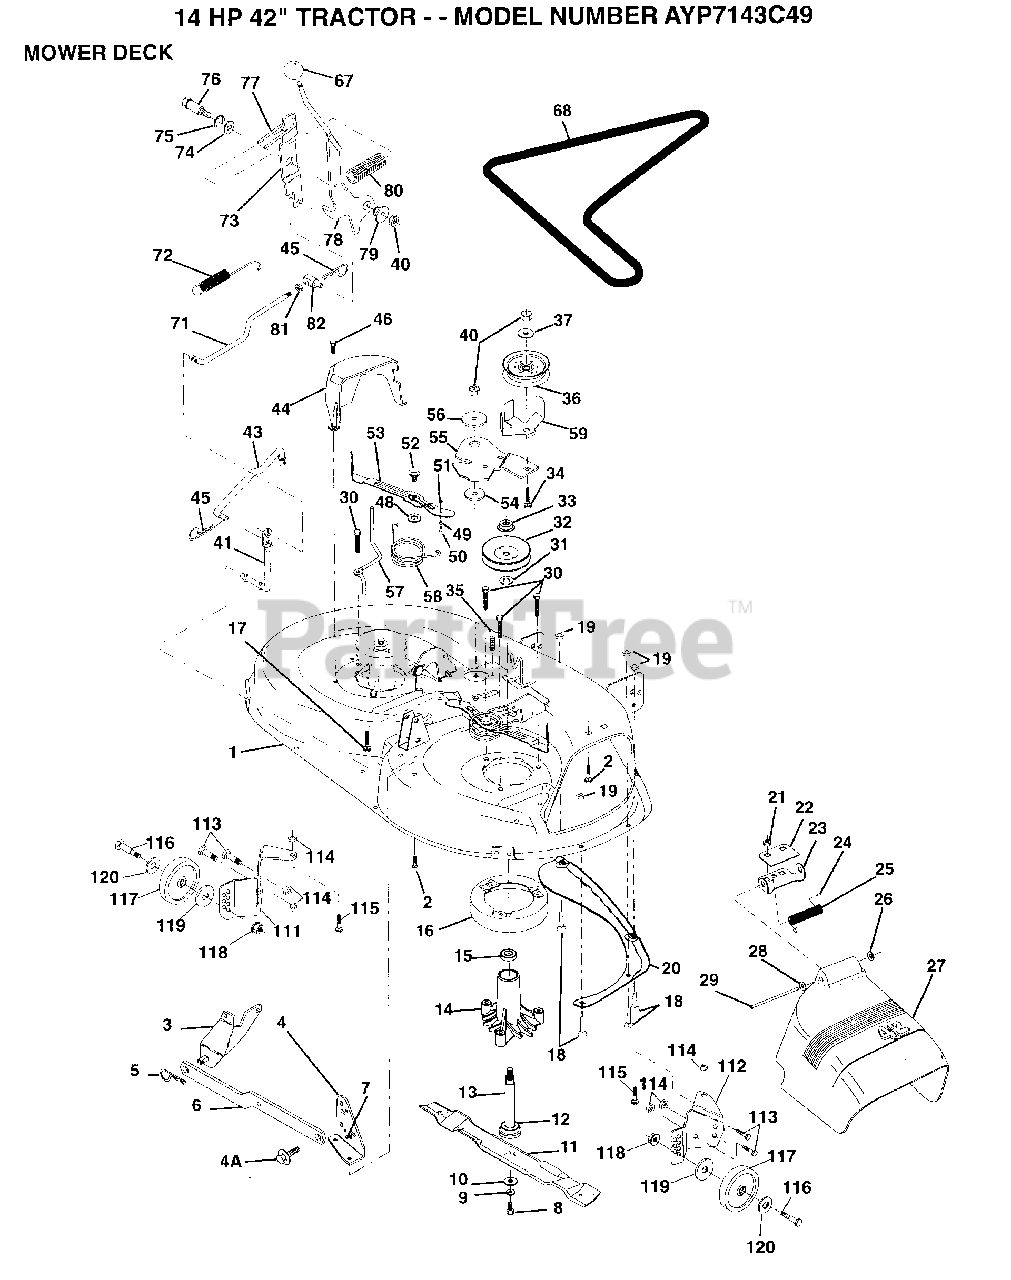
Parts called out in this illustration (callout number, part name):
2	BOLT
3	BRKT ASM SWAY BAR
4	BRKT DECK SW BAR
4A	BOLT SHD 5/16-18
7	NUT
8	BLADE BOLT
10	WASHER.HARD.BLADE
11	"BLADE.42"" MULCHER"
12	BEARING.BALL
14	HSG ASM MANDREL
15	BEARING
16	STRIPPER RND MWR
17	BOLT RDHD 3/8-16
18	BOLT
19	NUT
21	NUT
22	STIFFENER BRKT
23	DEFLECTOR BRKT
24	CAP-SLEEVE LT
25	SPRING TORSION
26	NUT PUSH M
27	DEFLECTOR.SHIELD
28	WASHER
29	HINGE ROD
31	WASHER
34	BOLT
35	XMAS TREE FASTNER
36	FLAT IDLER PULLEY
37	WASHER
40	NUT
41	PIVOT ROD
43	ROD CLUTCH W/NIBS
44	GUARD MAND LH BLK
45	RETAINER M
46	SCREW.1/4-20X5/8
48	HARD SMALL WASHER
50	SHOULDER BOLT
51	LOCKNUT
52	BOLT.SHLD.5/16-18
53	BRAKE PAD ARM ASM
54	HARDENED WASHER
56	SPACER RETAINER
57	KEEPER BELT LH 42
58	SPRING TORSN BRAK
59	GUARD IDLER TUV
67	KNOB T(3/8 HOLE)
68	BELT-V MWR 82.625
71	ROD CLUTCH 38/42
72	RETURN SPRING
73	CLUTCH ARM SECOND
74	WASHER
75	RING
76	SHOULDER BOLT
77	SPRING KEEPER
79	BUSHING
81	NUT
82	TRUNION ADJ
113	BOLT
116	BOLT M
117	WHEEL.GAGE.BLK.PL
118	LOCKNUT
119	WASHER
120	WASHER
